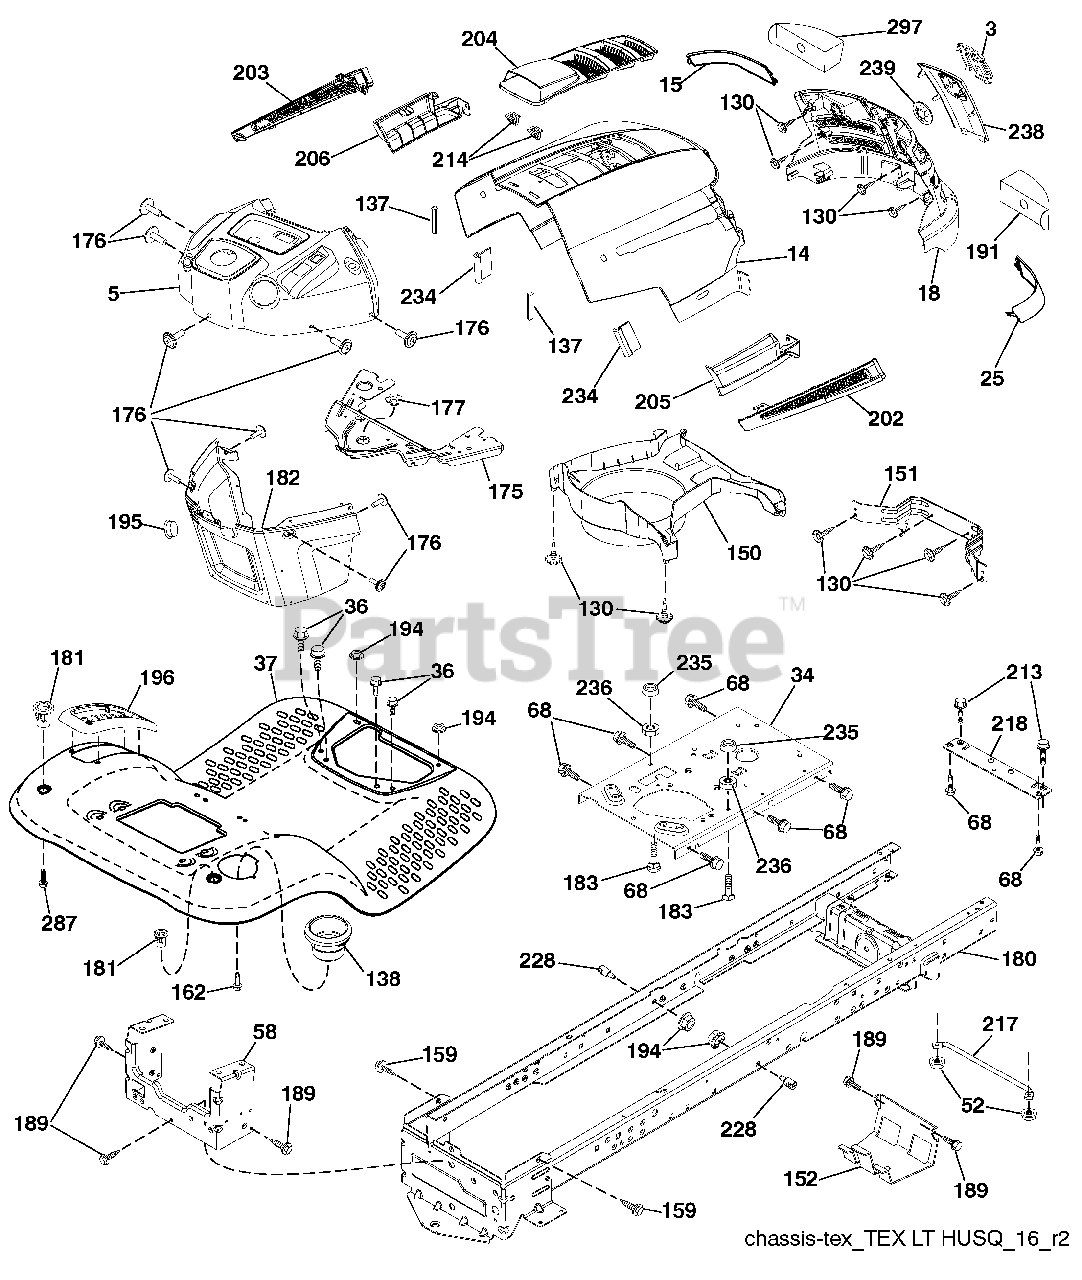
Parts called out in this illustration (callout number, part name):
3	Logo
5	Dash
14	Hood
15	Lens LH
18	Grille
25	Lens RH
34	Plate Engine
36	Screw 5/16-18 x 3/4
37	Fender
52	Nut Crown Lock 5/16
58	Drawbar Upper
68	Screw THDROL 5/16-18 x 1/2
130	Screw #10 x 0.750 BOS Thread
137	Bumper Dash
138	Cupholder
151	Bracket Pivot
152	Shield Browning
159	Screw Hexwash Thor 3/8-16 x 3/4
175	Crossmember Plate
176	Screw 10-24 x 5/8
177	Bushing Steering
181	Bushing Mtg. Fender Crgo
182	Dash Lower
183	Bolt 5/16-18 x 1-1/4 Full Thd
189	Screw 5/16-18 x 3/4
191	Insert Reflective RH
194	Nut Lock Hex Flange 5/16-18
195	Plug Dash
196	Console Asm. Deck Lift
202	Vent Side Hood RH
203	Vent Side Hood LH
204	Vent Top Hood
205	Skirt Side RH
206	Skirt Side LH
213	Bolt 5/16-18 x 3/4
214	Clip Retainer
217	Rod Pivot Hood
218	X-Piece Hood Stop
228	Stud Fastener
234	Bumper Hood
235	Spacer Fender
236	Nut Lock 5/16-18 unc
238	Trim
239	Clip Tinnerman
287	Screw Hex Washead 1/4-20 x 3/8
297	Insert reflective LH
